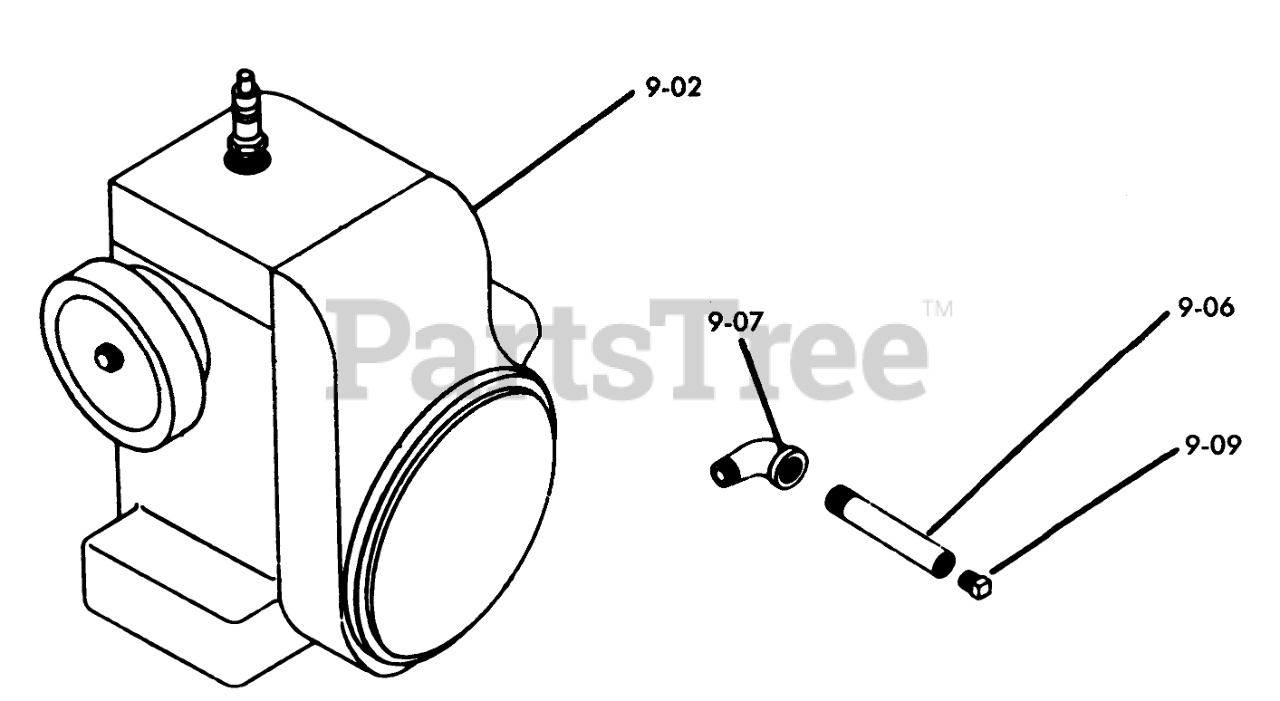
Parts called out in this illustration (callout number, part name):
9-02	Engine-12HP Kohler
9-02	Engine-1OHP Kohler
9-02	Engine-16HP Kohler
9-02	Engine-8HP Kohler
9-02	Engine-7HP Kohler
9-02	PLATE COIL & SOL MTG
9-02	Engine Base
9-02	BOLT
9-02	NUT
9-02	LOCKWASHER
9-06	Nipple 3/8 x 5
9-07	ELBOW-STREET
9-09	Cap
